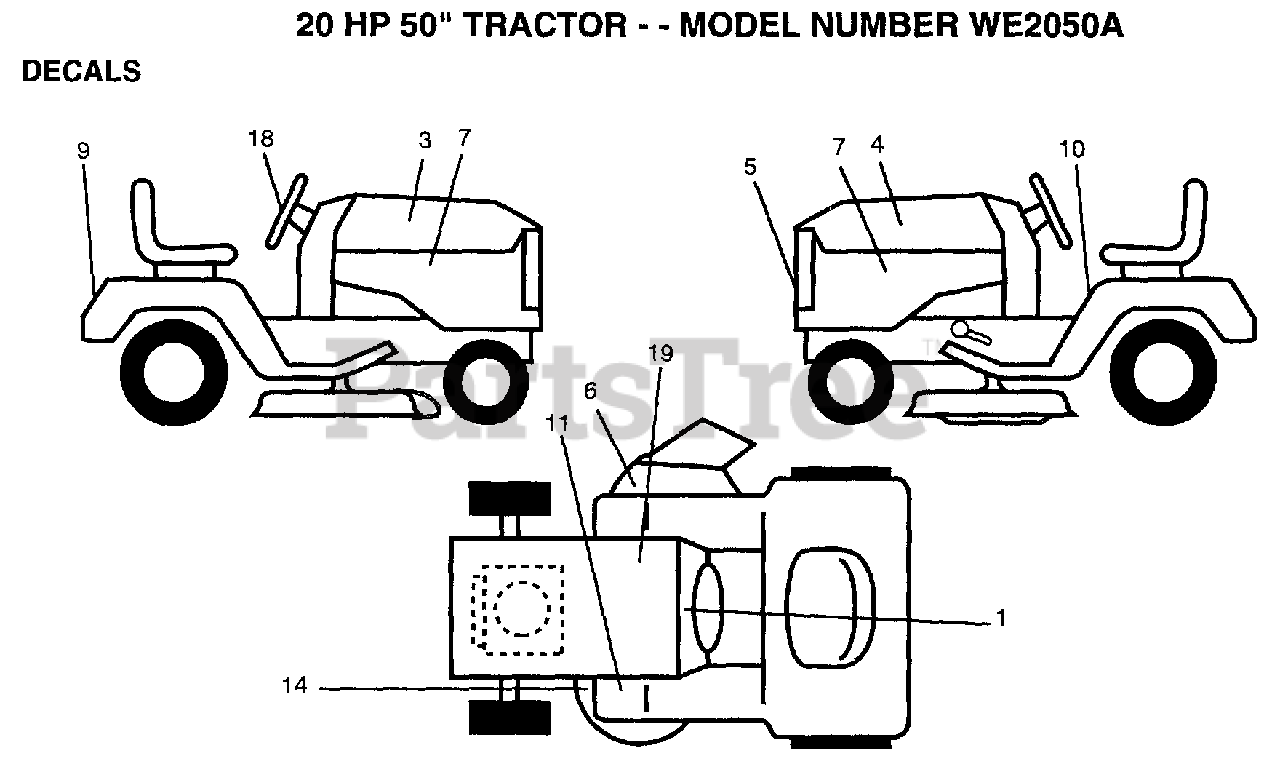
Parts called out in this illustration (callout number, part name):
1	DECAL INST OP DAS
3	DECAL.HD.B&S.RH
4	DECAL.HD.B&S.LH
5	DECAL.GRILL
6	"DECAL, WARNING"
7	DECAL.PANEL.SIDE
9	DECAL.FENDER
10	DECAL CAUT FEND
11	DECAL CLUT/BRAKE
14	"DECAL.V.BELT.44"""
18	DECAL.INS.STRG.WH
19	DECAL
